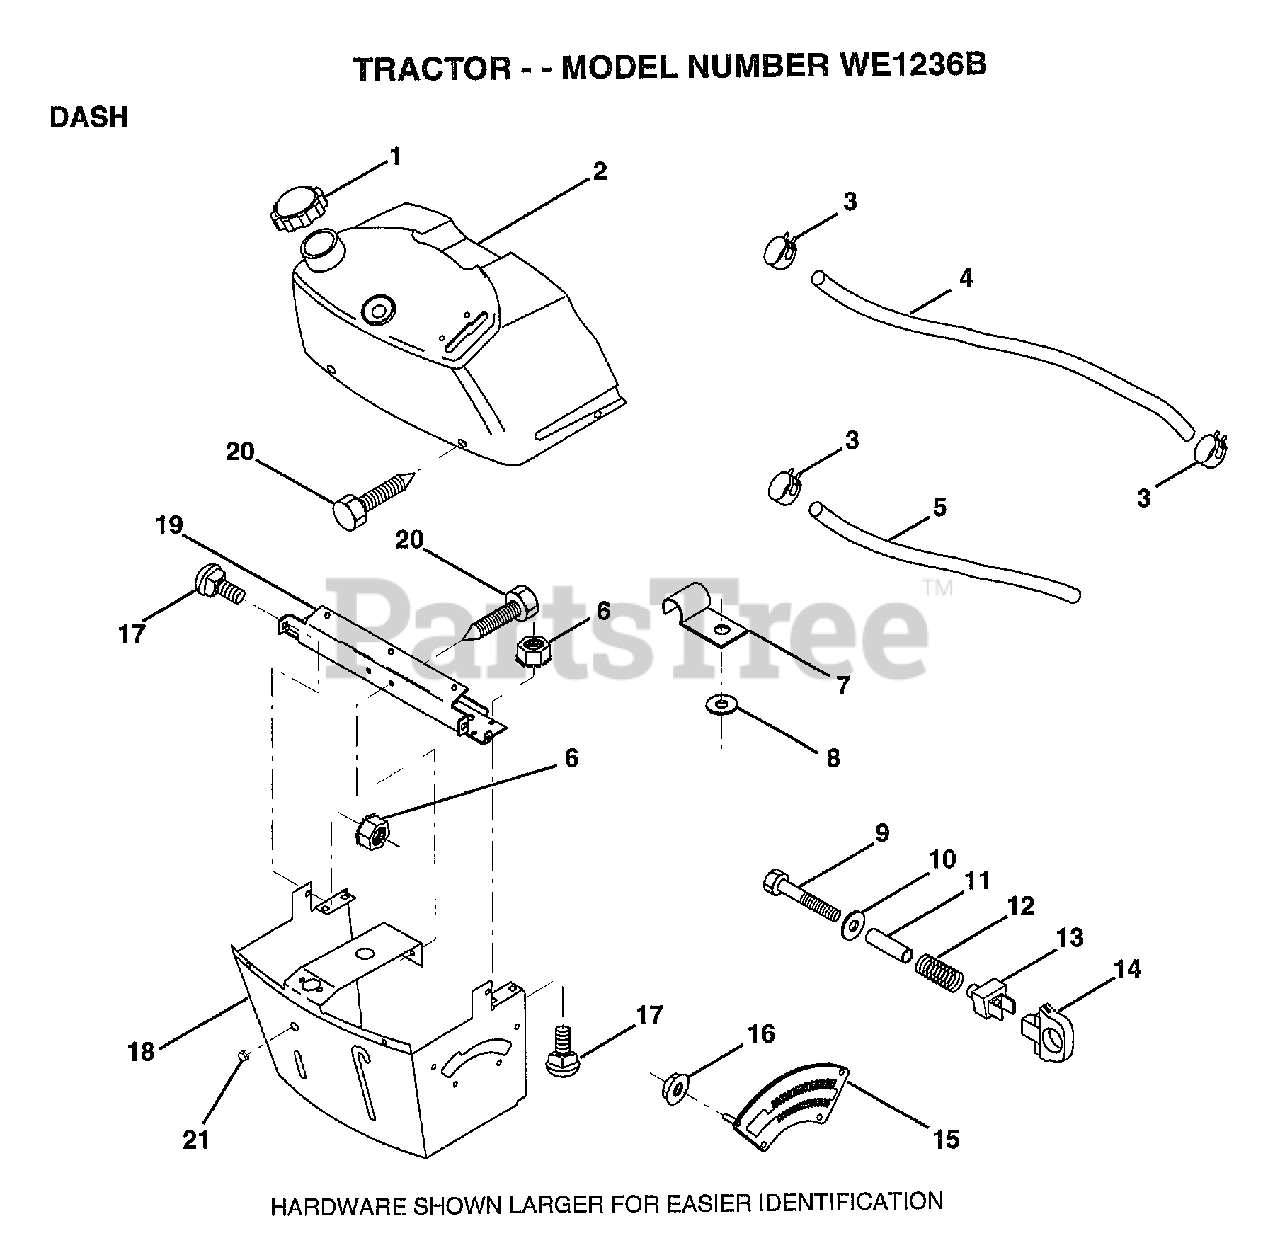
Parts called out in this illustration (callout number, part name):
1	CAP BLK FUEL LR
2	TANK.ASM.DASH.LR
3	HOSE CLAMP
5	FUEL LINE T
6	NUT
7	CLIP T
8	WASHER PM
9	BOLT
11	SPACER SPLIT
12	SPRING M
13	"KNOB,HGT RETAINER"
14	KNOB
15	ADJUSTER QUAD
16	NUT
17	BOLT
18	SUPT ASSY DASH
19	CROSS BRACE
20	SCREW.1/4-20X1/2
21	PLUG DOME
